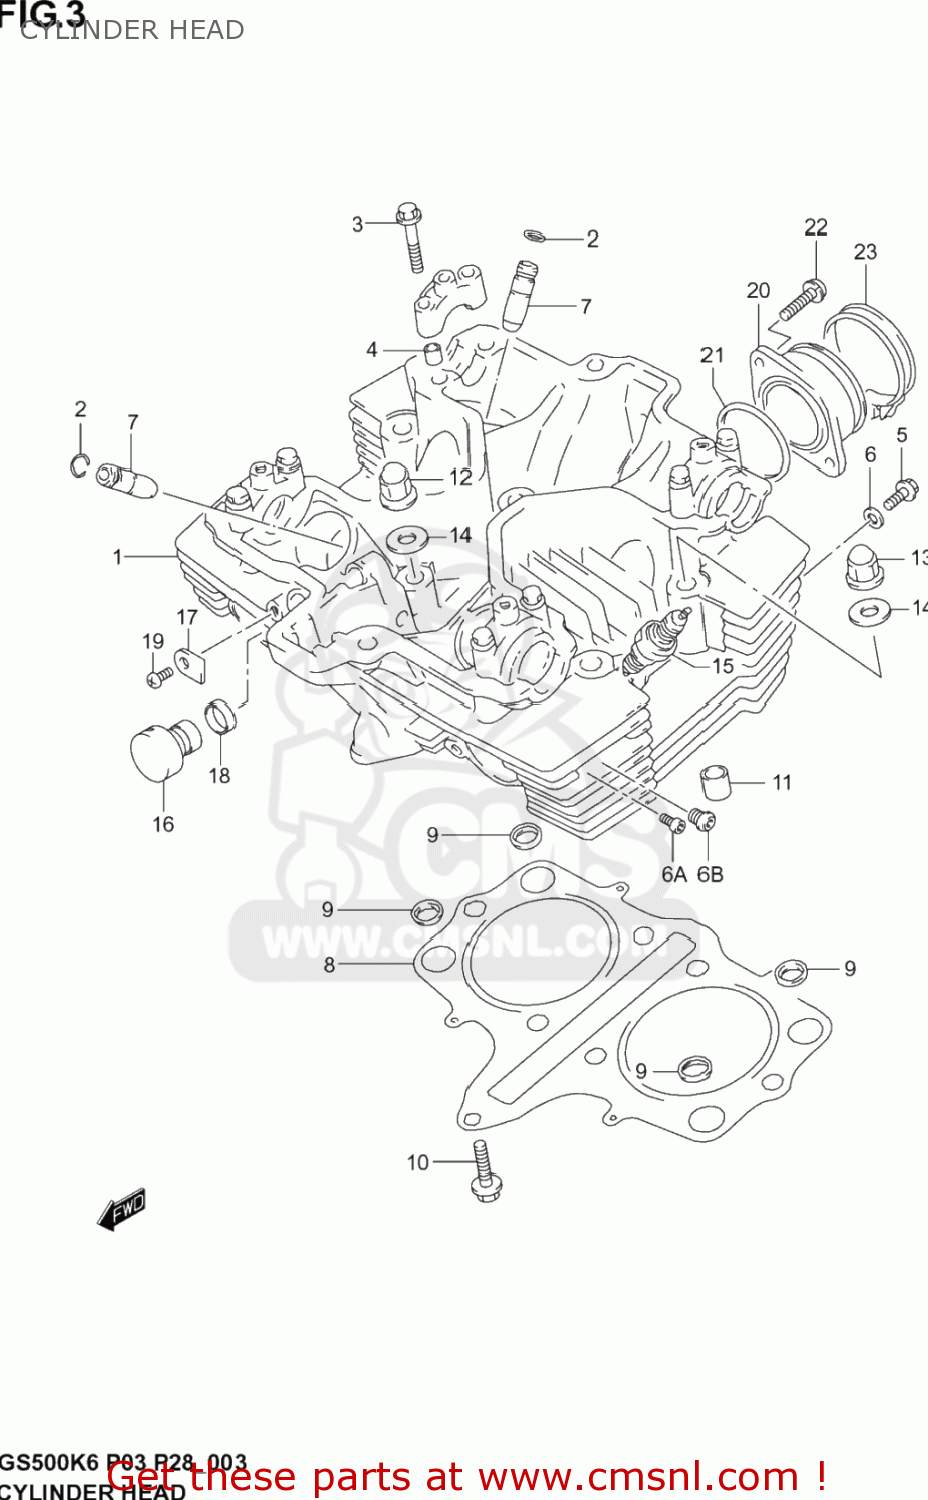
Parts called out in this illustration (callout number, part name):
1	HEAD ASSY,CYLINDER
2	RING,SNAP
3	BOLT(6X39)
4	PIN(6.2X8X11)
5	BOLT
6	GASKET(5.8X13X1.2) (NAS)
6A	BOLT(6X12)
6B	PLUG(10X10)
7	GUIDE,INTAKE VALVE
8	GASKET,CYLINDER HEAD (NAS)
9	O RING,HEAD GASKET
10	BOLT
11	PIN
12	NUT
13	NUT
14	GASKET(10.2X20X2).3 (NAS)
15	PLUG,SPARK(DPR8EA-9)
16	PLUG,TACH GEAR SLEEVE HOLE
17	PLATE,TACH DRIVE GEAR SLEEVE
18	SEAL,TACHOMETER DRIVEN
19	SCREW(5X12)
20	PIPE ASSY,INTAKE
21	O RING(D:2.4,ID:39.7)
22	SCREW
23	CLAMP
